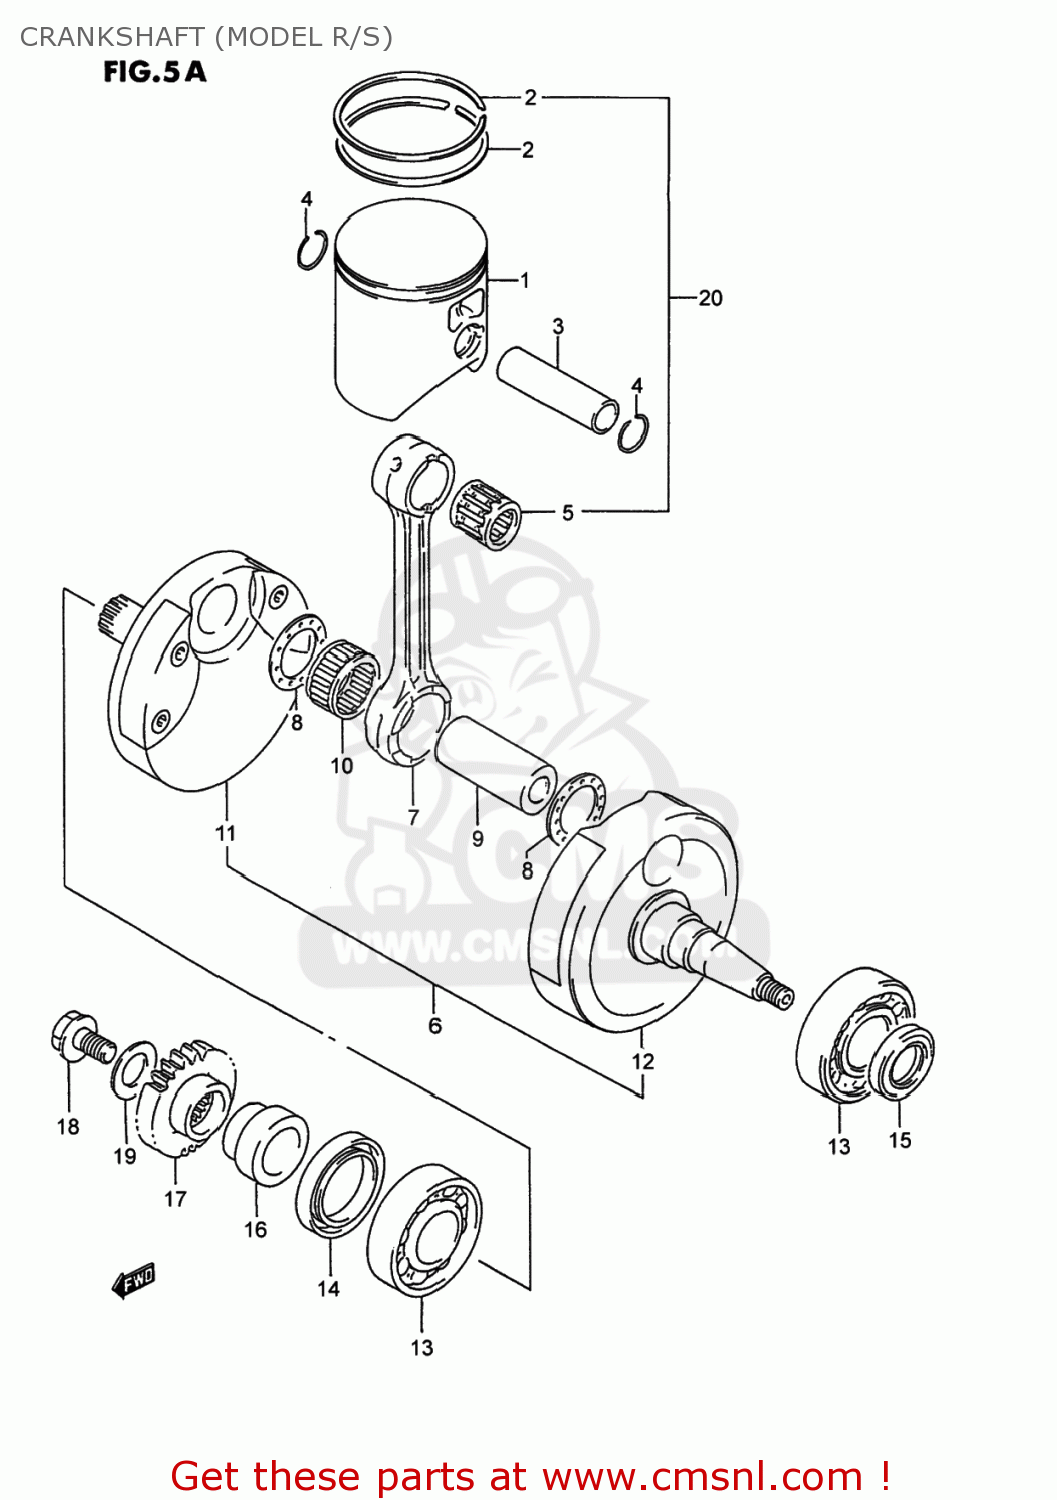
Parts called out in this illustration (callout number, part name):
1	PISTON COMP
2	RING,PISTON
3	PIN,PISTON
4	CIRCLIP
5	BEARING(18X23X22)
6	CRANKSHAFT ASSY
7	ROD,CONNECTING
8	WASHER(24X38.5X1.5)
9	PIN,CRANK
10	BEARING(24X30X20)
11	CRANKSHAFT,R
12	CRANKSHAFT,L
13	BEARING(28X68X18)
14	SEAL,OIL(38X52X8)
15	SEAL,OIL(20X37X6)
16	SPACER,PRIMARY DRIVE GEAR
17	GEAR,PRIMARY DRIVE (NT:
18	BOLT,PRIMARY DRIVE GEAR
19	WASHER
20	TOP END KIT,ENGINE
